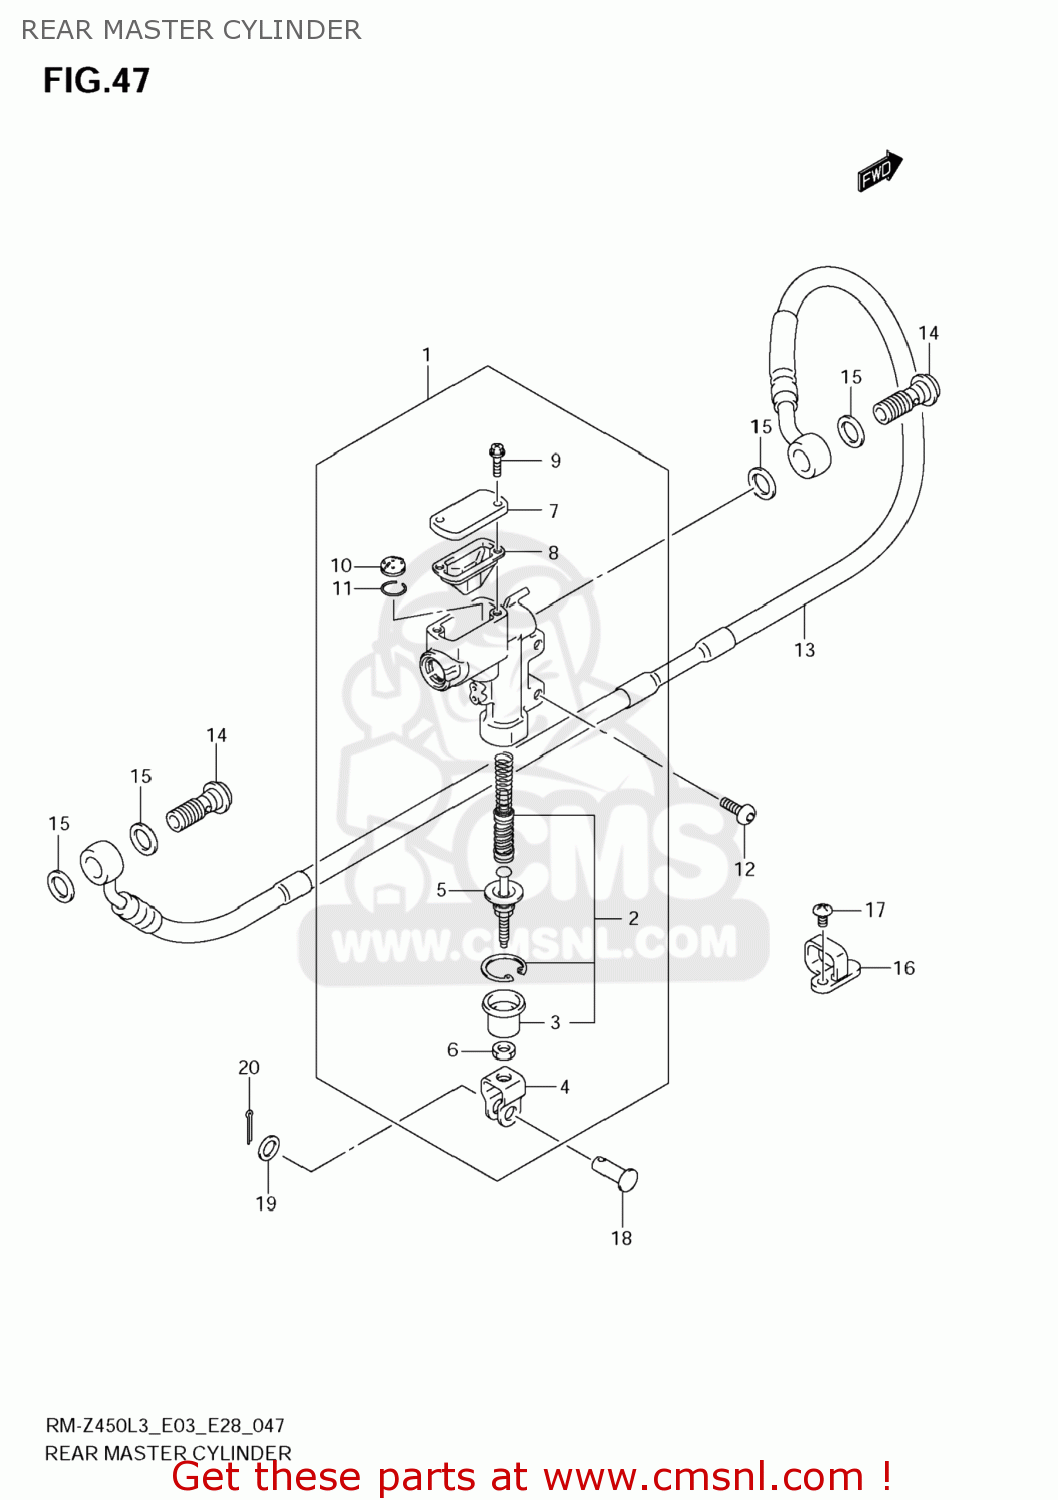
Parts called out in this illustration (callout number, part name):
1	CYLINDER ASSY,RR MASTER
2	PISTON / CUP S
3	BOOT
4	YOKE
5	ROD,PUSH
6	NUT
7	CAP
8	DIAPHRAGM
9	SCREW
10	SEPARATOR
11	RING
12	SCREW(6X16)
13	HOSE,RR BRAKE
14	BOLT UNION
15	WASHER(10X15X1.5)
16	GUIDE,RR BRAKE
17	SCREW
18	PIN(8X20)
19	WASHER(8.5X14X1.6)
20	PIN
